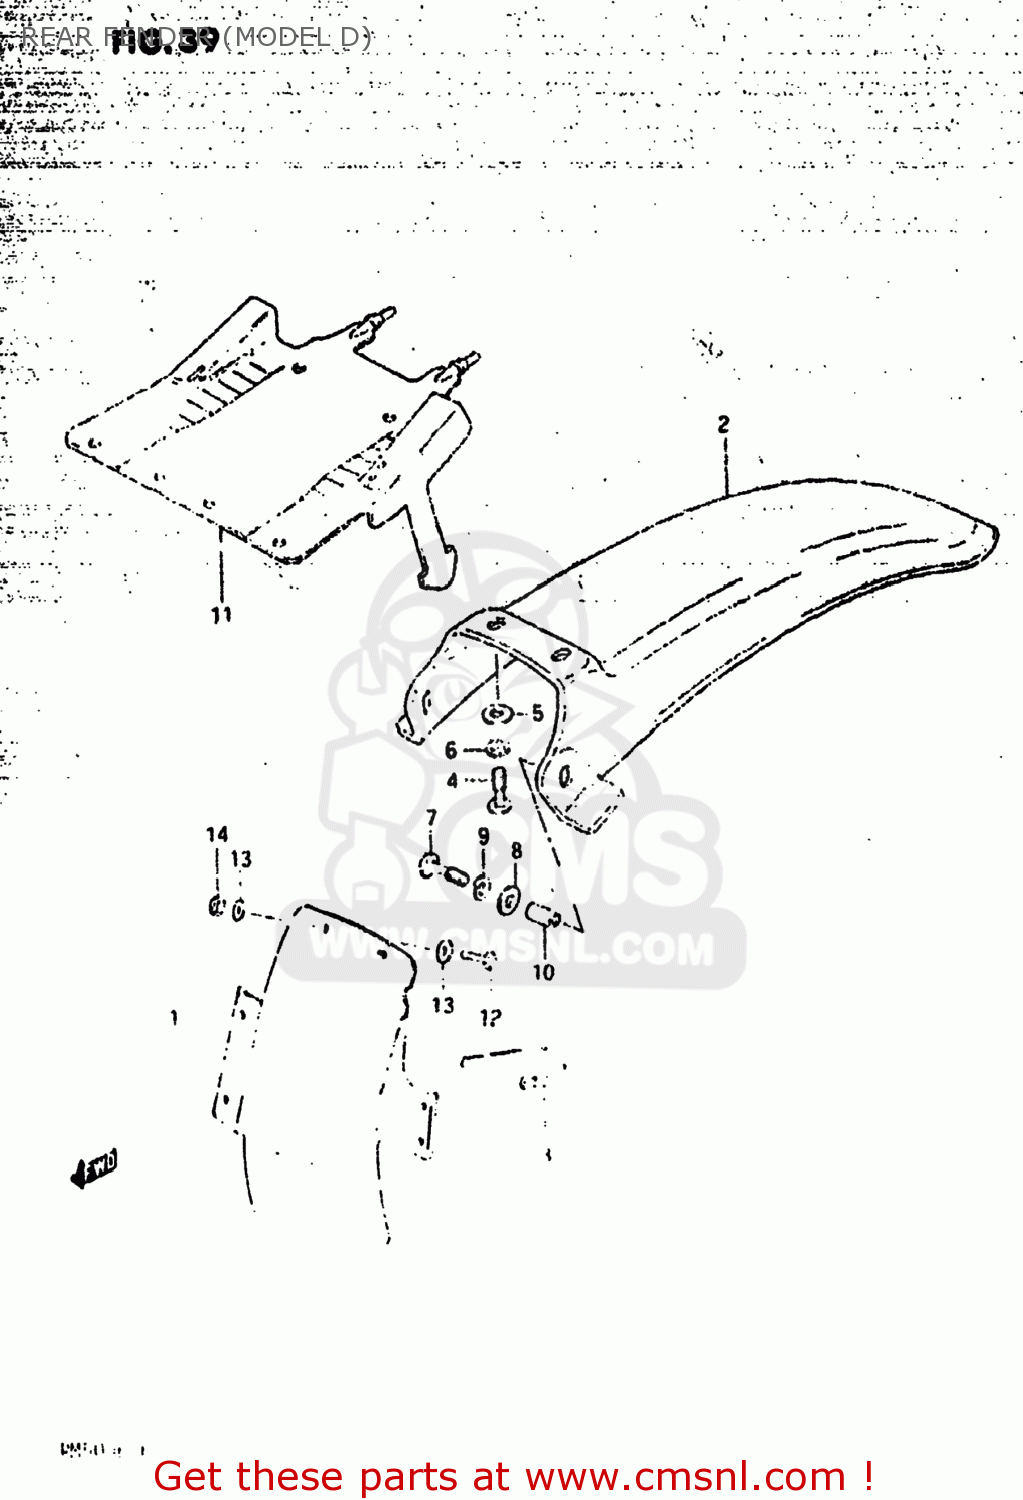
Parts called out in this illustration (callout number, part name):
1	FENDER,REAR
2	FENDER,REAR
3	CLAMP
4	SCREW
5	WASHER
6	LOCK WASHER
7	BOLT, UPPER
8	WASHER (6.5X20X1.2)
9	LOCK WASHER
10	SPACER
11	GUIDE,RR FENDER MUD
12	SCREW
13	WASHER
14	NUT
